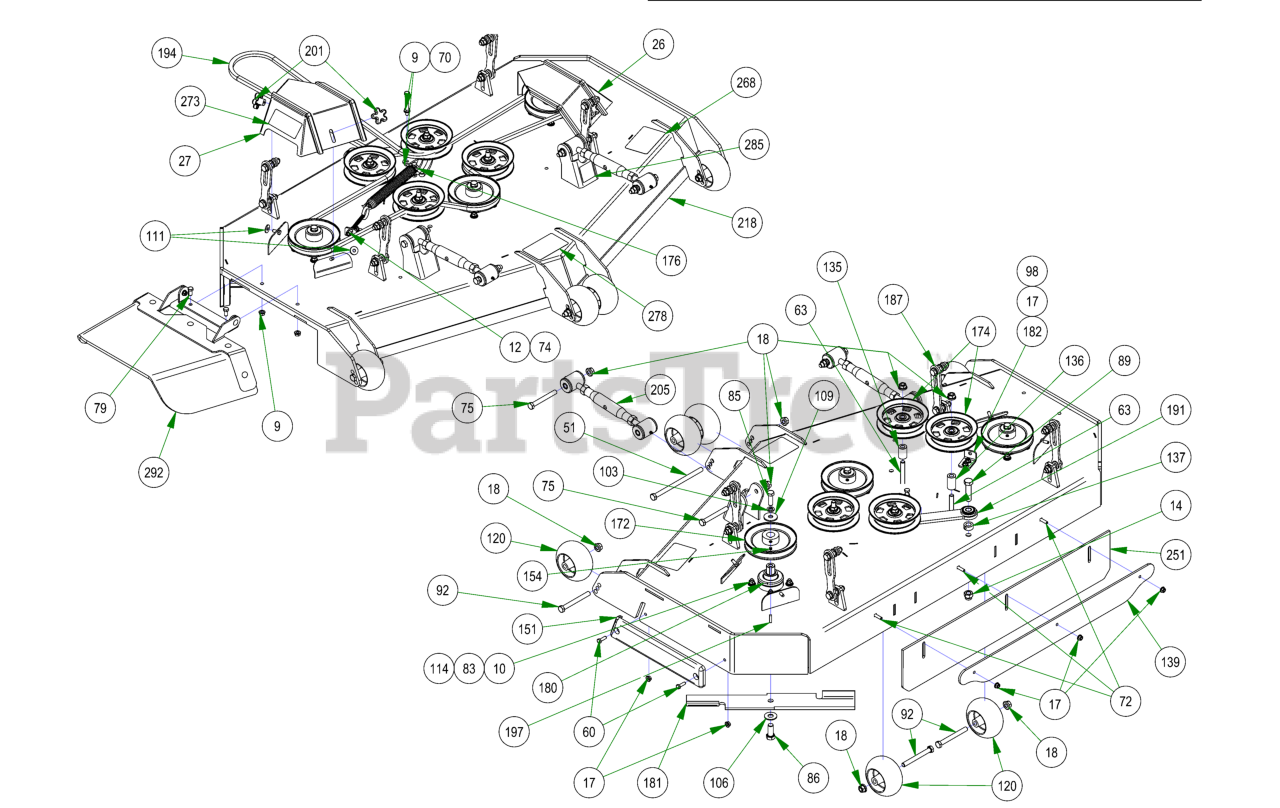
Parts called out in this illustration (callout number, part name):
9	3/8-16 HEX SERRATED FLANGE NUT HARD/ZINC
10	3/8-16 NYLON INSERT FLANGE LOCKNUT (GR.F) ZINC
12	3/8-16 HEX NUT ZINC
14	5/8-11 NYLON INSERT LOCKNUT ZINC
17	5/16-18 NYLON INSERT FLANGE LOCKNUT ZINC
18	1/2-13 NYLON INSERT FLANGE LOCKNUT ZINC
26	2019 61" Outlaw Gen2 Pulley Cover Left
27	2019 61" Outlaw Gen2 Pulley Cover Right
51	1/2-13 X 8 HEX CAP SCREW GR 5 ZINC
60	5/16-18 X 1 HEX CAP SCREW (GR.5) ZINC
63	1/2-13 X 3-1/2 HEX FLANGE BOLT (GR.8) ZINC
70	3/8-16 X 3 HEX CAP SCREW (GR.5) ZINC
72	5/16-18 X 1-1/4 CARRIAGE BOLT ZINC
74	4" 3/8-16 Eye Bolt
75	1/2-13 X 4 HEX CAP SCREW (GR.8) ZINC YELLOW
79	3/8-16 X 3/4 HEX CAP SCREW (GR.5) ZINC
83	3/8-16 X 1-1/2 HEX CAP SCREW (GR.5) ZINC
85	1/2-20 X 1-1/2 HEX CAP SCREW (GR.5) ZINC
86	5/8-18 X 1-1/2 HEX CAP SCREW (GR.8) ZINC YELLOW
89	5/8-11 X 2-1/2 HEX CAP SCREW (GR.5) ZINC
92	1/2-13 X 4-1/2 HEX CAP SCREW (GR.5) ZINC
98	5/16-18 X 7/8 CARRIAGE BOLT ZINC
103	1/2 SPLIT LOCKWASHER (GR.8) ZINC/YELLOW
106	5/8 USS FLAT WASHER (1-3/4" OD) GR.8 ZINC YELLOW
109	1/2 BELLEVILLE WASHER (1-5/8 OD X .140 THK) ZINC
111	.360 ID X .983 OD X .120 THICK FLAT WASHER NYLON BLACK
114	5/16 USS FLAT WASHER (7/8 OD) ZINC
120	2019 Deck Wheel
135	.502 ID X .750 OD X 1.500 Long Spacer
136	1 3/4" Pulley Spacer
137	5/8 SOLID SHAFT COLLAR (W/1 SET SCREW) ZINC
139	61 Bolt in Baffle Deck v2 Stripping Plate
151	REVISED TRIM BUMPER_20180226
154	5/16-24 X 1/4 SOCKET SET SCREW (CUP PT) PLAIN
172	6 1/4" Drive Pulley
174	5-3/4 Idler Pulley
176	2019 Outlaw Gen2 Deck Spring
180	OUTLAW SPINDLE ASSEMBLY
181	61 inch Fusion Blade
182	2019 Deck Eye Bolt Tab
187	Deck Hanger Assembly
191	2019 Renegade Deck Idler
194	Deck Belt for 61" Renegade
197	1/4 X 1 SQ MACHINERY KEY 1018 STL PLN
201	5/16" Knob
205	Turnbuckle
218	2019 Sloped 61" Deck
251	R Series Rubber For Deck
268	2018 61" Deck Decal
273	Danger Decal-Spindle/Discharge
278	2019 Renegade Deck Belt Route Decal
285	Deck Impact Patent Decal 9591803
292	2019 Outlaw Gen2 Chute Assembly
